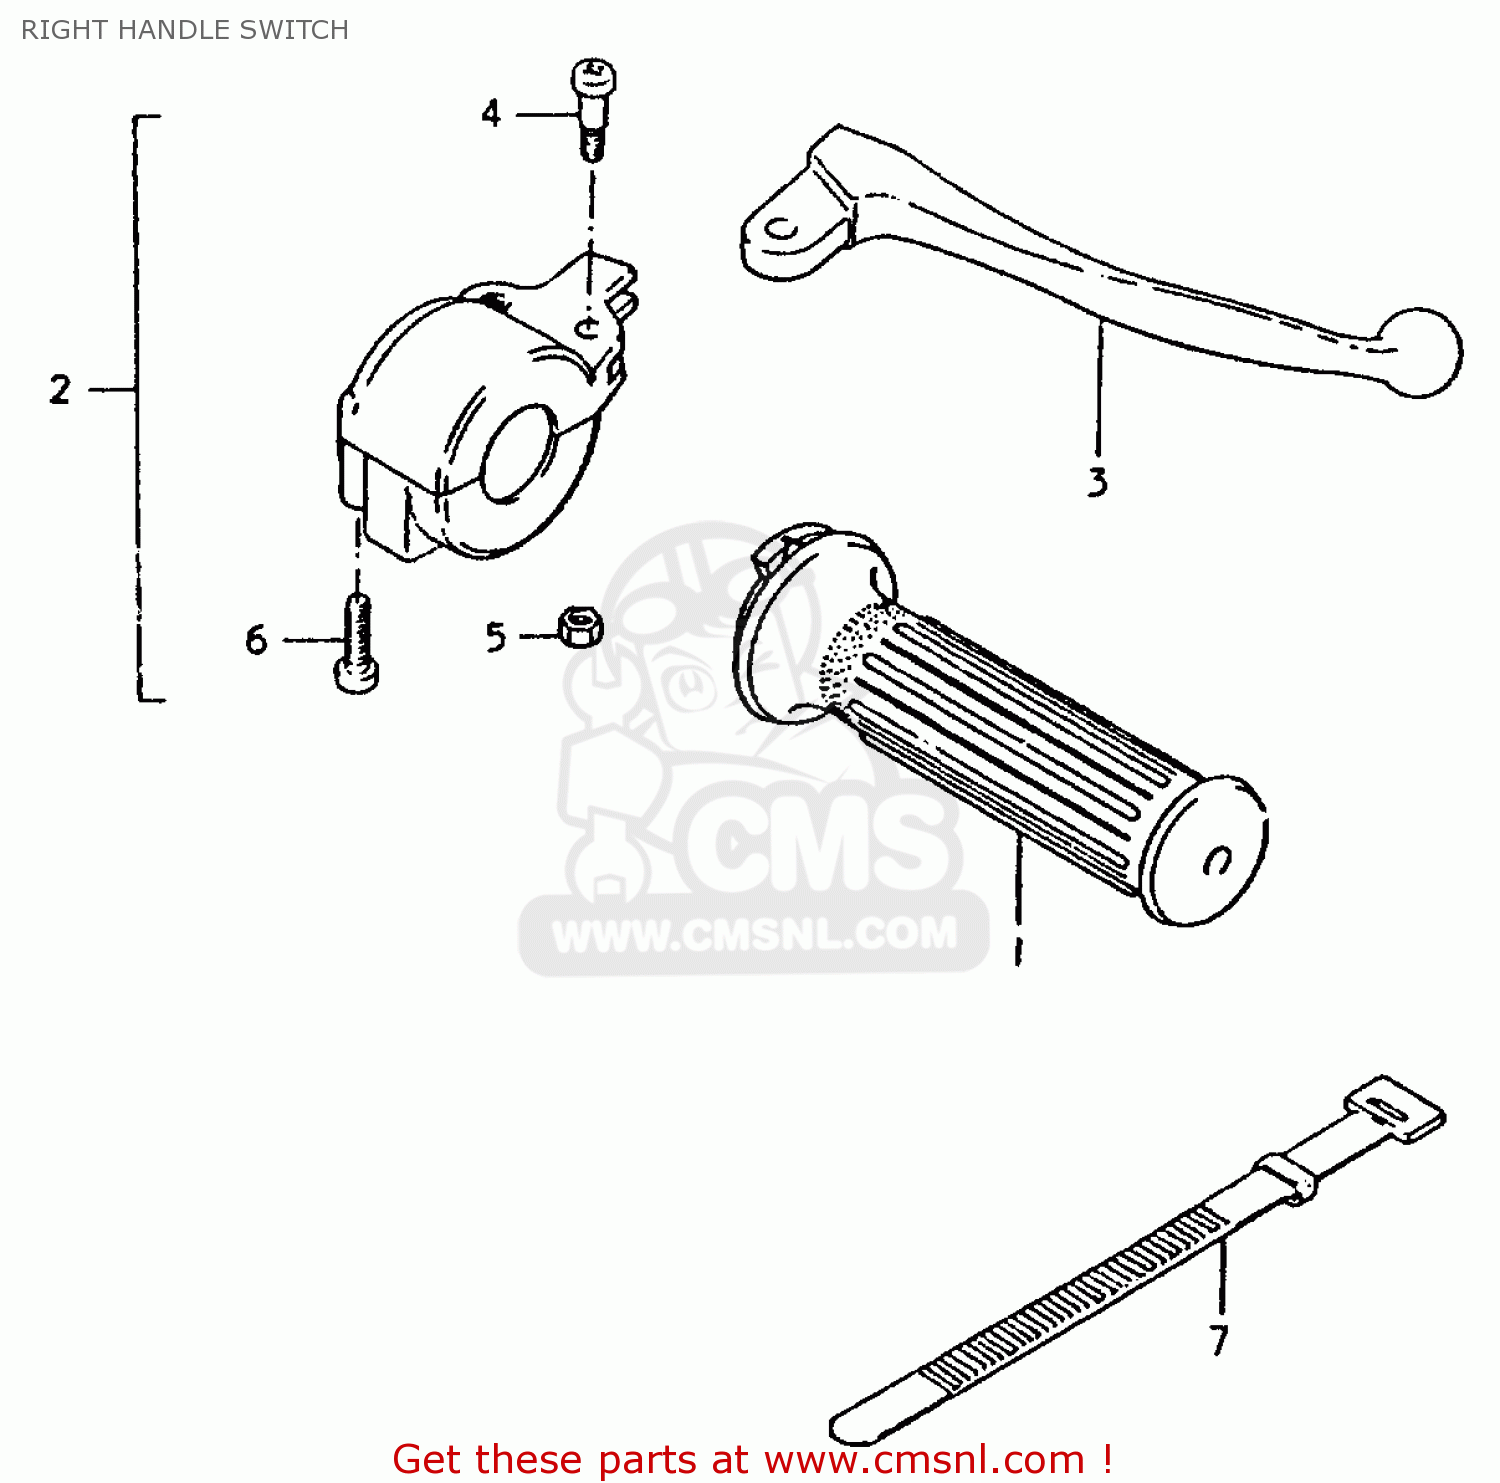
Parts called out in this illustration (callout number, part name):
1	GRIP,THROTTLE
2	BRAKE LEVER & SWITCH ASSY
3	LEVER
4	BOLT,LEVER
5	NUT,LEVER BOLT
6	SCREW
7	CLAMP(L:120)
